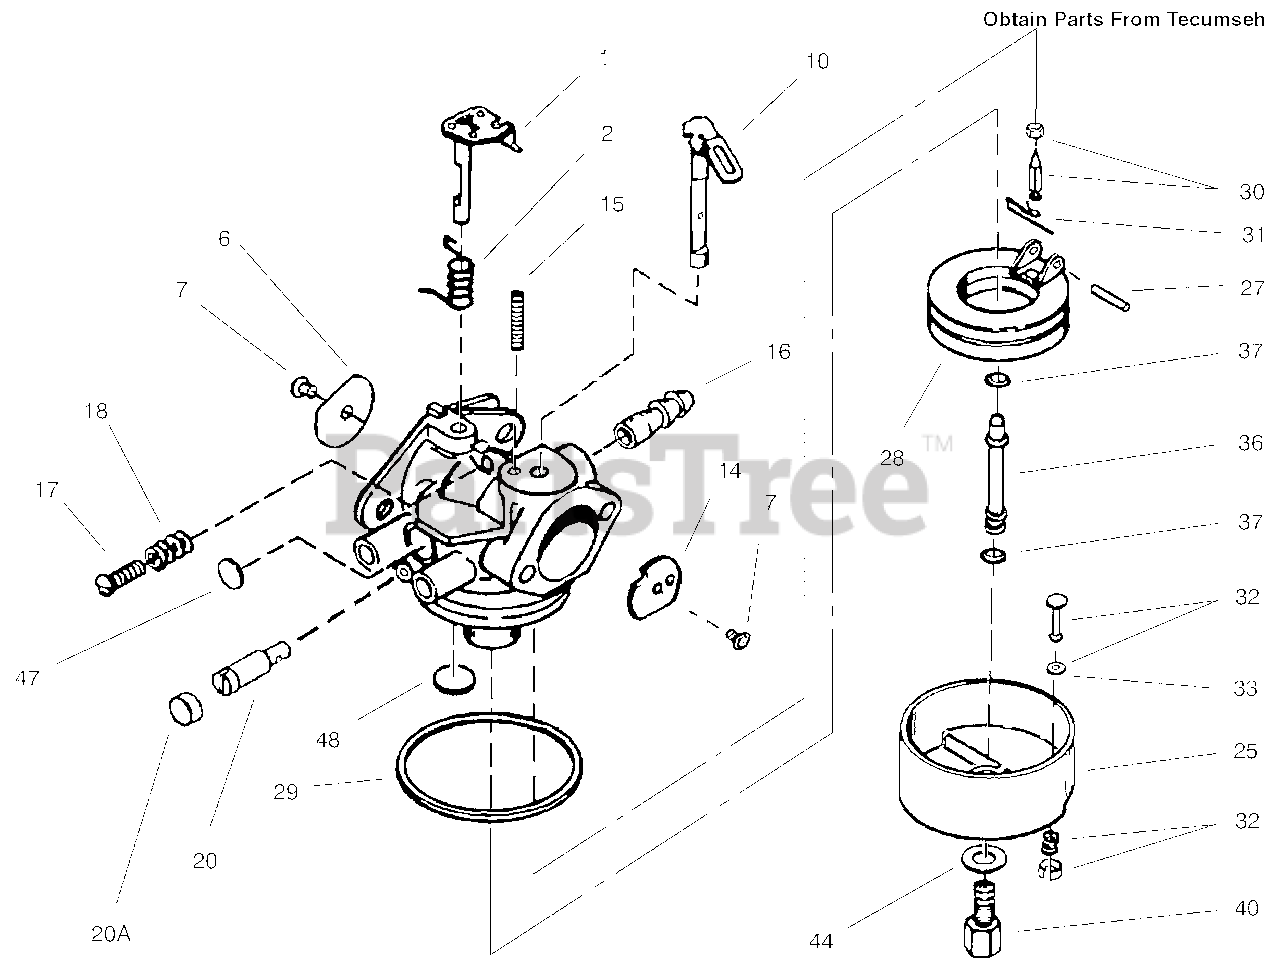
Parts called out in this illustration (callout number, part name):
1	Shaft/Lever-Throttle
2	Spring-Throttle Return
6	Shutter-Throttle
7	Screw-Shutter
10	Shaft/Lever-Choke
14	Shutter-Choke
15	Spring-Choke Positioning
16	Fitting-Fuel Inlet
17	Screw-Idle Regulating
18	Spring-Tension
20	Screw-Idle Adjustment
21	Cap-Screw Idler Adj.
25	Float Bowl Assembly (Incl. Ref. #32 & 33)
27	Shaft-Float
28	Float-Carburetor
29	Gasket-Bowl to Body
30	Inlet Needle, Seat & Clip Asm (Incl. Ref. #31)
31	Clip-Inlet Needle
32	Drain Assembly (Incl. Ref. #33)
33	Gasket-Bowl Drain
36	Main Nozzle Tube
37	O-Ring-Main Nozzle Tube
40	High Speed Bowl Nut
44	Gasket-Bowl to Body
47	Plug-Welch
48	Plug-Welch
